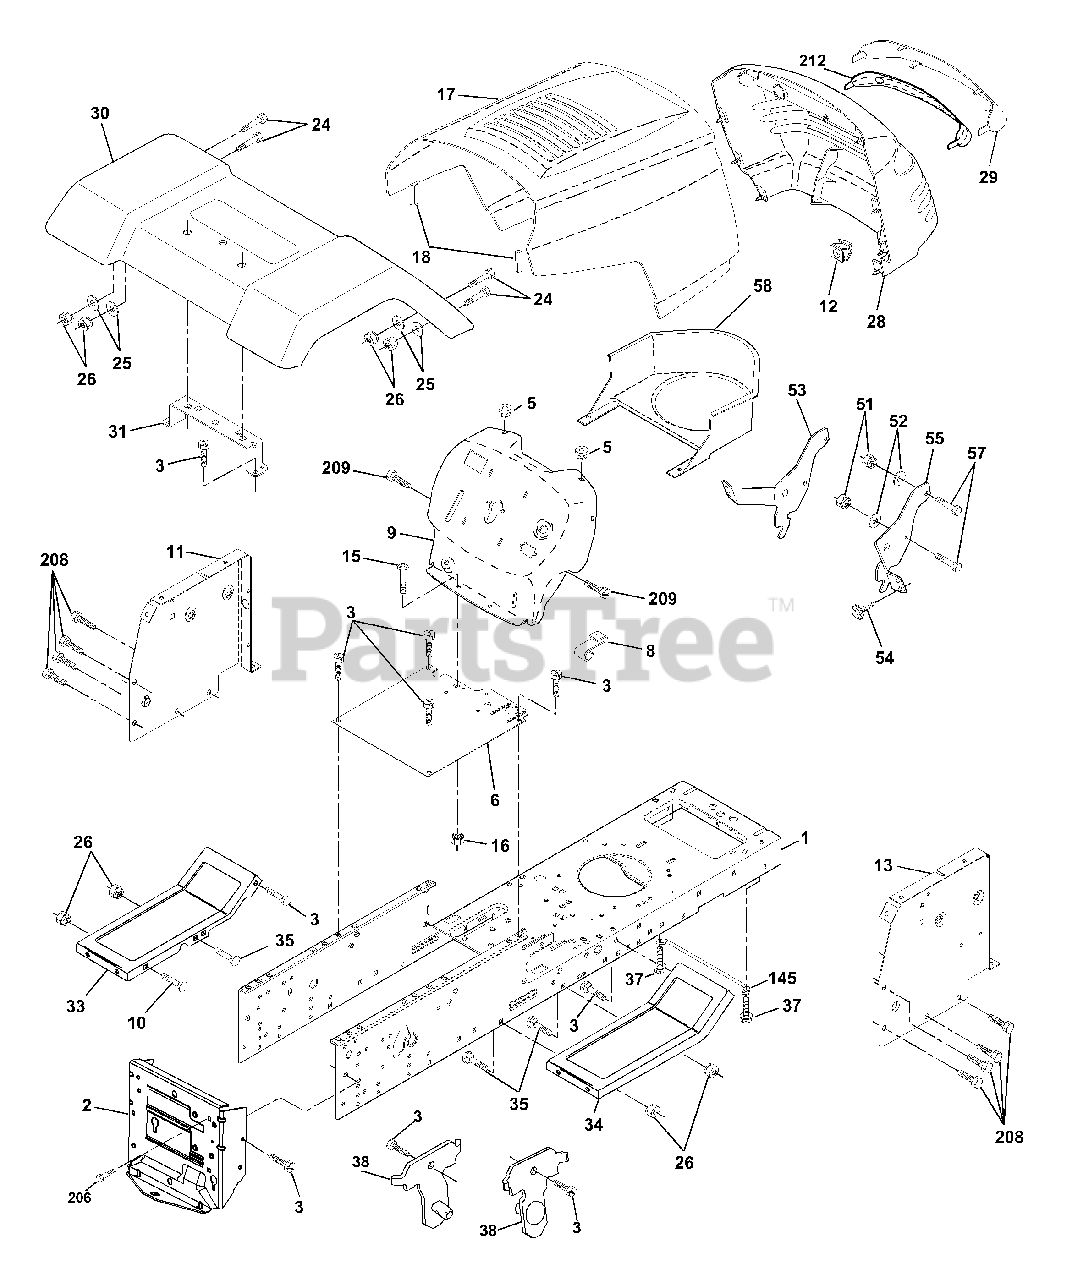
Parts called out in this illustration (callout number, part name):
2	Drawbar, Stretch
3	Screw 3/8-16 x 3/4
5	Bumper, Hood/Dash
6	Saddle Silkscreen Flt Sdl
8	Clip Retainer Slide-On
9	Dash
10	Bolt, Carriage 3/8-16 x 1
11	Panel Dash LH
12	Clip Tinnerman Grille P.L
13	Panel Slkscr Dash RH
14	Screw Thdrol 3/8-16x1/2 Ty-tt
15	Screw Mach TRHD 5/16-18uncx3/4
16	Nut Keps 5/16-18 Unc
17	Hood
18	Bumper Hood
24	Bolt Fin Hex 3/8-16unc X 1 Gr. 5
25	Washer 13/32 X 13/16 X 12 Ga
26	Nut Lock Hex w/Ins 3/8-16 Unc
28	Grille P.L Ms 428
29	Lens Grille Private Label
30	Fender
31	Bracket Fender Repl 109873x
33	Footrest Pnt LH Perf
34	Footrest Pnt RH Perf
35	Bolt Rdhd Sht Sqnk 3/8-16 X3/4
37	Screw Thdrol 5/16-18 x 1/2 TYT
38	Bracket Asm. Pivot Mower Rear
51	Nut Lock W/Insert 1/4-20unc
52	Washer 9/32 x 7/8x16 Ga.
53	Bracket Grille Lh
54	Screw Hex 8-18 x 7/8
55	Bracket Grille Rh
57	Bolt Fin Hex 1/4-20 unc x .75
58	Duct Air Engine PL/LT
145	Rod Pivot Chassis/Hood
206	Bolt Shoulder 5/16-18
208	Screw Thdrol 3/8-16 x 1/2
209	Screw Hex Wsh Thdrol 3/8-16
212	Insert Lens Reflect
